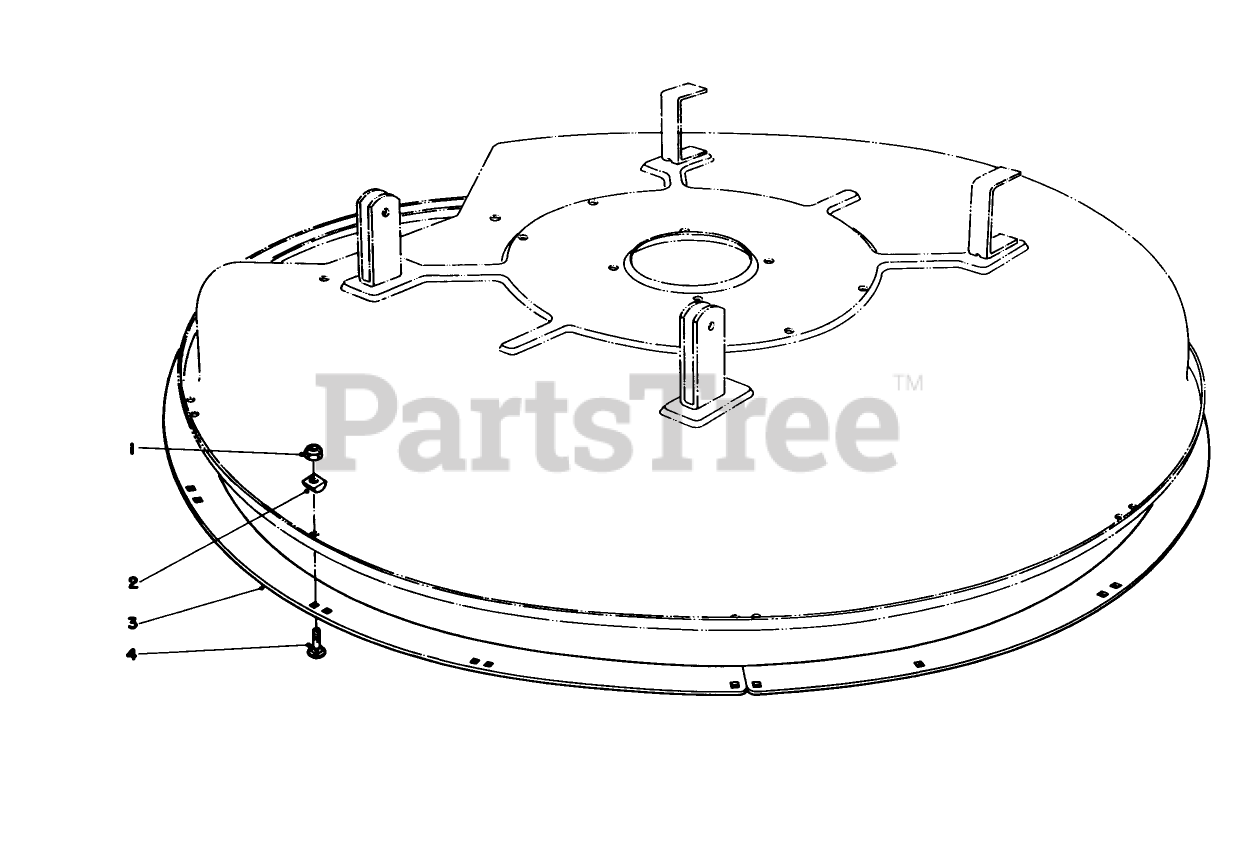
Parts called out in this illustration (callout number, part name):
1	NUT-LOCK, NI
3	DECK RING *B
4	BOLT-CARR
